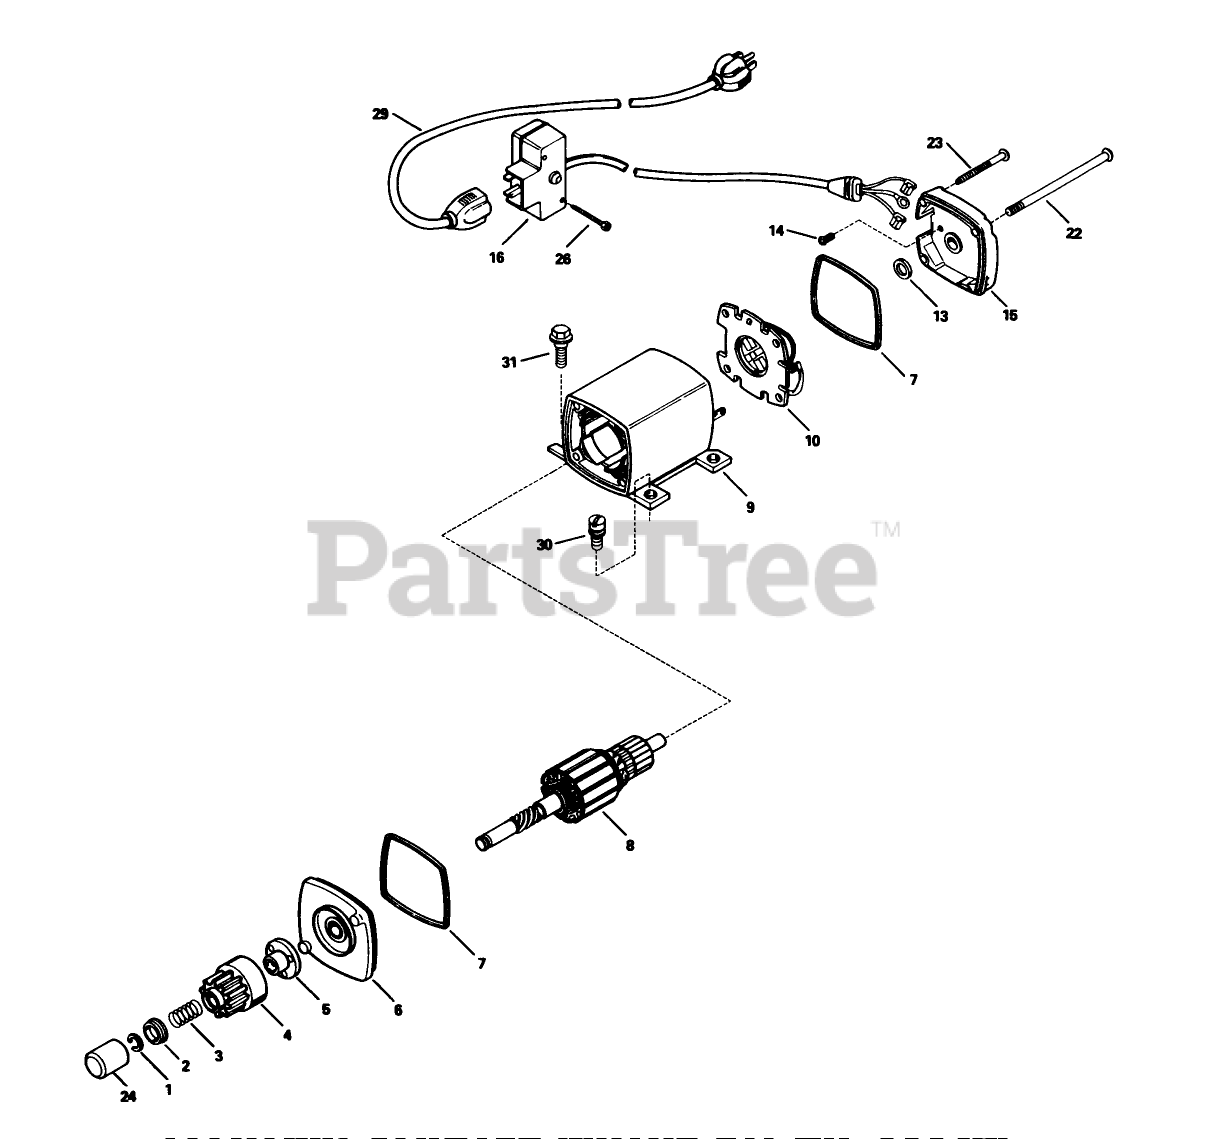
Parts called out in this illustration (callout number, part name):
1	Ring-Retainer
2	Retainer-Spring
3	Spring-Anti Drift
4	Gear
5	Nut-Engaging
6	Cap Assembly-Cap End (Incl. Ref. #7)
7	O-Ring
8	Armature
9	Housing Assy.
10	Card ASM
13	Washer-Thrust
14	Screw-Ground
15	Cap Assembly (Incl. Ref. #7)
16	Box Assembly-Switch (Incl. Ref. #26)
22	Bolt-Case
23	Screw-Ground
24	Cover-Dust
26	Screw
29	Cord-Extension
30	Screw
31	Screw (1/4-20x1/2)
